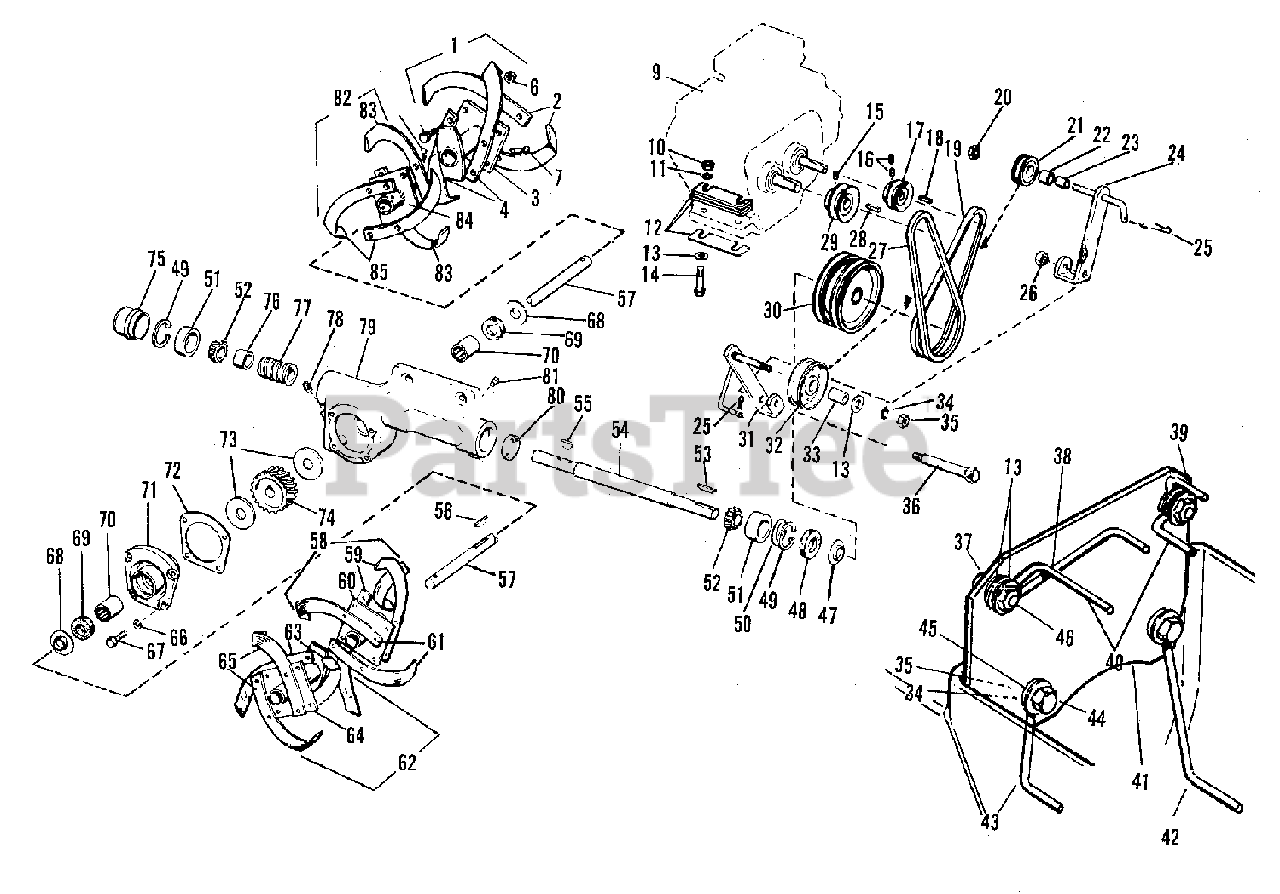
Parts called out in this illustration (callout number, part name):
1	BLADE ASSEMBLY, Tine, Outer (R.H.)
2	BLADE, Tine (L.H.)
3	PLATE, Tine, Outer
4	BLADE, Tine (R.H.)
5	SCREW, Hex Cap, 7/16-20 x 1-1/4
6	NUT, Hex, 7/16-20
8	PIN, Cotter, 1/8 x 3/4
9	ENGINE, 5 H.P.
10	NUT, Hex, 5/16-18
11	WASHER, Lock, 5/16"
12	SHIM, Engine
13	WASHER, Flat, 5/16
14	SCREW, Hex, Cap, 5/16-18 x 2
15	SCREW, Set, 5/16-18 x 3/8
16	SCREW, Set, 5/16-18 x 5/16
17	PULLEY, Engine
18	KEY, Woodruff, #5
20	NUT, Hex, 3/8-16
21	PULLEY, Idler
24	LEVER, Idler
25	PIN, Cotter, 3/16 x 1
26	NUT, Special, Hex, 5/16-18
29	PULLEY, Engine
30	PULLEY, Driven
31	LEVER, Idler
32	PULLEY, Idler
34	WASHER, Lock, 3/8"
35	NUT, Hex, 3/8-16
37	BOLT, Carriage, 3/8-16 x 1
44	SCREW, Hex, Cap, 3/8-16 x 1
45	WASHER, Flat, 3/8
46	NUT, Hex, 3/8-16
50	RING, Backing
51	CUP, Bearing
52	BEARING, Roller
55	KEY, Hi-Pro, 3/16 x 7/8
56	KEY, Woodruff, #91
57	SHAFT, Worm Gear
58	BLADE ASSEMBLY, Tine, Inner (L.H.)
59	BLADE, Tine (L.H.)
60	PLATE, Tine, Inner
61	BLADE, Tine (R.H.)
62	BLADE ASSEMBLY, Tine, Outer (L.H.)
63	BLADE, Tine (L.H.)
64	PLATE, Tine, Outer
65	BLADE, Tine (R.H.)
66	WASHER, Lock, 1/4
67	SCREW, Hex Cap, 1/4-20 x 5/8
70	BEARING, Needle
73	WASHER, Thrust
74	GEAR, Worm (R.H.)
77	WORM, Right Hand
78	PLUG, Pipe, 3/8"
79	HOUSING, Worm Drive
82	BLADE ASSEMBLY, Tine, Inner (R.H.)
83	BLADE, Tine (L.H.)
84	PLATE, Tine, Inner
85	BLADE, Tine (R.H.)
